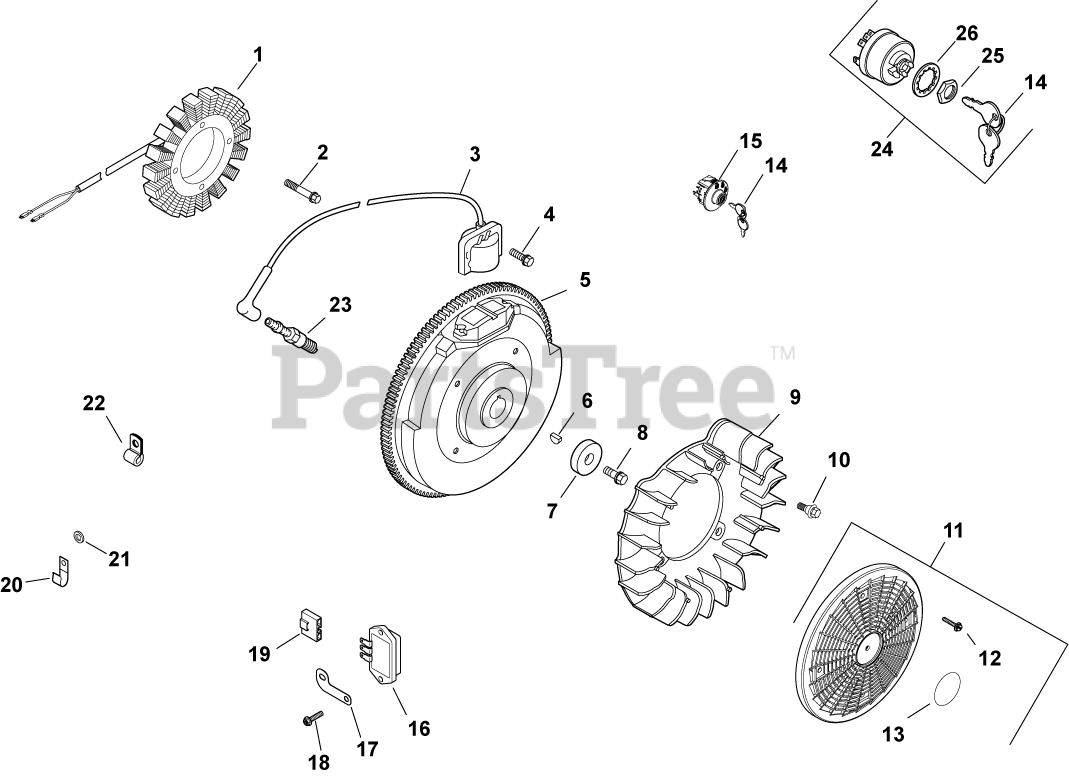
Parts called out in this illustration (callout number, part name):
1	KIT, 15 / 20 AMP STATOR
2	SCREW, M5X0.8X25 - (#25086402S)
3	KIT, MODULE IGNTN (CDI FIXED)
4	SCREW, FLG THD FRM M5X.8X20-(#25086399S)
6	KEY, 3/16" X 5/8"
7	WASHER, FLAT 13/32"
8	SCREW, FLG M10X1.5X45 - (#25086361S)
9	FAN USE 24 755 253-S
10	BOLT, SHOULDER
11	KIT, GRASS SCREEN
12	SCREW, FLG SEMS M4X.7X25
13	DECAL, GRASS SCREEN USE 24 113 499-S
14	KEY, SET OF 2
15	KIT, KEY SWITCH (SNAP-IN)
16	REGULATOR, RECTIFIER USE 25 403 32-S
17	BRACKET, GROUND STRAP USE 24 518 12-S
18	SCREW, HEX FLANGE HI-LO
19	CONNECTOR
20	CLIP, CABLE
21	WASHER, FLAT 1/4" (O.D. 1/2")
23	SPARK PLUG, RFI
24	SWITCH ASSY, KEY (KM)-USE 25 099 32-S
25	NUT, KEY SWITCH
26	WASHER, INTERNAL TOOTH
